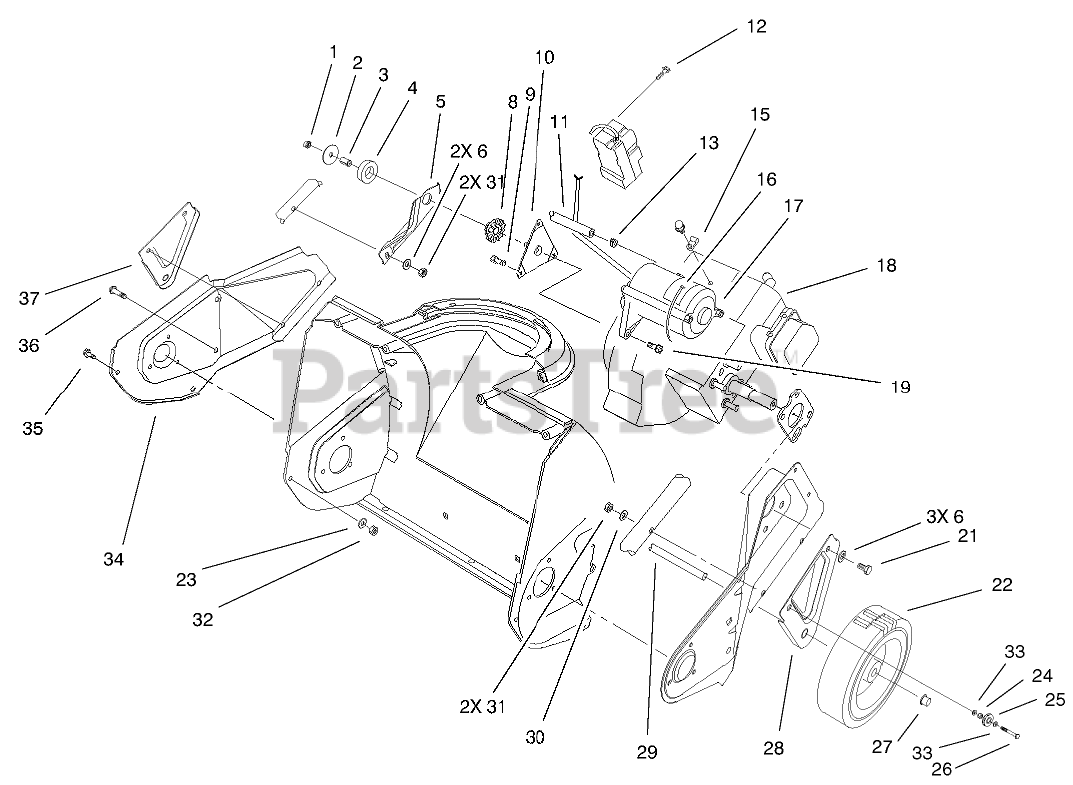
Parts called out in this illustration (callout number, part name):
1	NUT-LOCK, NI
2	WASHER-FLAT
3	SPACER-TUBULAR
4	RING-ISOLATOR
5	BRACKET-SUPPORT, ENGINE
6	WASHER-FLAT
8	BUSHING-ISOLATOR
9	SCREW
10	BRACKET AND STUD ASM
11	LINE-GAS
12	SCREW-PLASTITE
13	CLAMP-HOSE
15	CLAMP
16	TIE-CABLE
17	STARTER ASM (230 VOLT)
19	SCREW-HH, TORX
21	SCREW-HH
22	WHEEL
23	WASHER-FLAT
24	SPACER-BLADE, ROTOR
25	CABLE-PULLEY
26	SCREW-HH
27	RETAINER-PUSH ON
28	BRACKET-WHEEL, LH
30	WASHER
31	NUT-LOCK, NI
32	NUT-LOCK, NI
33	WASHER-FLAT
34	PLATE-SIDE, RH
36	SCREW-PLASTIC
37	BRACKET-WHEEL, RH
